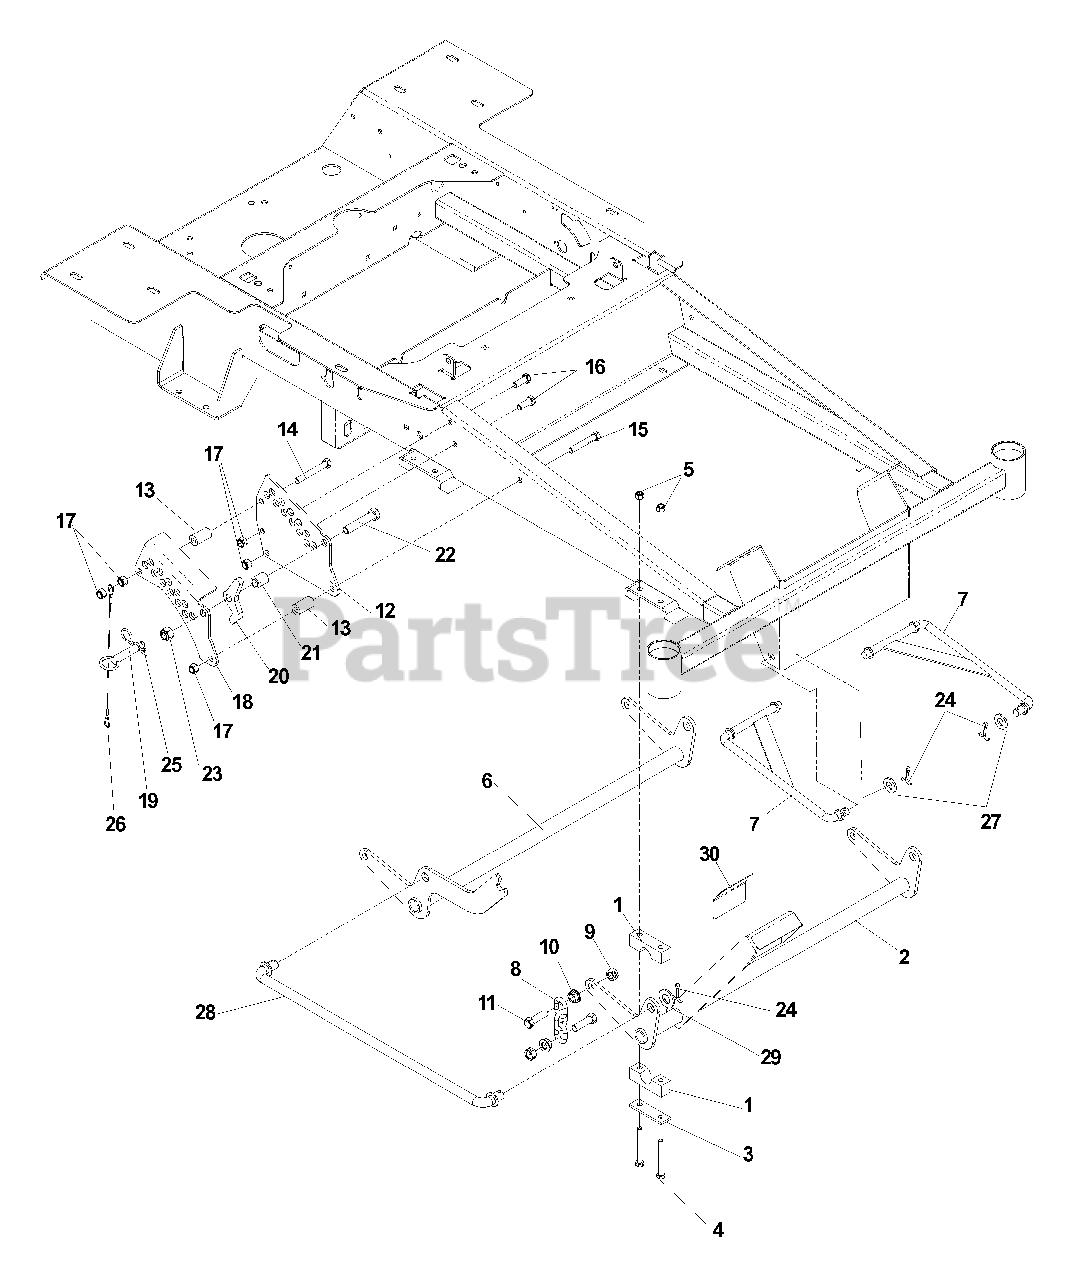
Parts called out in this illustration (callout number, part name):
1	PILLOW BLOCK
2	FRONT LIFT SHAFT
3	REINFORCEMENT BAR
4	HCS, 5/16-18 X 2 3/4, GR5
5	NUT, 5/16-18, NYLOC
6	REAR LIFT SHAFT
7	STRUT LINKAGE
8	LIFT CHAIN, 3 LINKS
9	NUT, 7/16-14, CENTERLOCK
10	NUT, 7/16-14, WHIZLK
11	HCS, 7/16-14 X 1 1/2, GR5
12	HEIGHT ADJUST PLATE
14	HCS, 3/8-16 X 2 3/4, GR5
15	HCS, 3/8-16 X 2 1/4, GR5
16	HCS, 3/8-16 X 1, GR5
17	NUT, 3/8-16, NYLOC
18	HEIGHT ADJUSTMENT PLATE, OUTER
20	PAWL, STOP
22	HCS, 1/2-13 X 2 1/2, GR5
23	NUT, 1/2-13, NYLOC
24	COTTER PIN, 5/32 X 1.25
25	HAIRPIN, #4
27	WASHER, 1/2, SAE
28	DECK LIFT LINK
29	WASHER, 5/8, SAE
30	ANTI-SKID PAD
